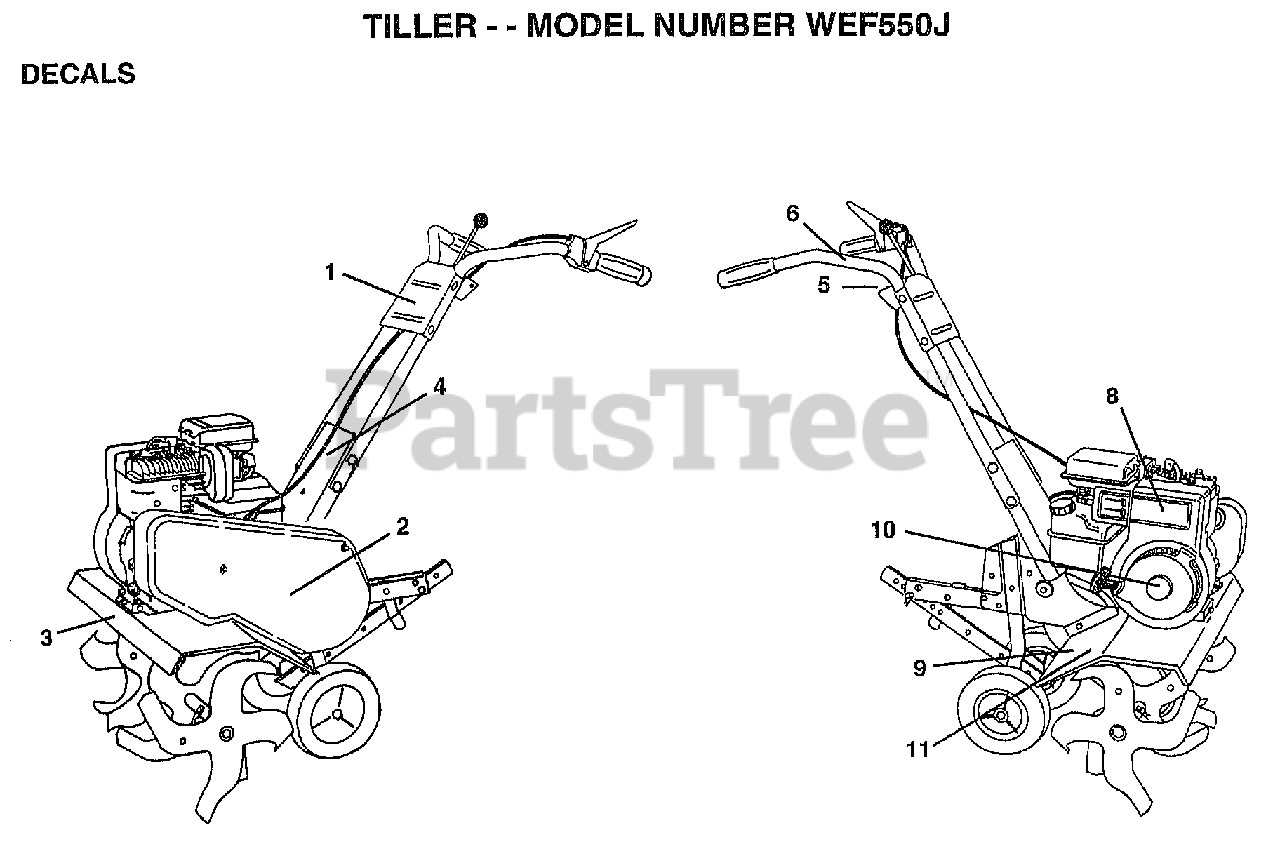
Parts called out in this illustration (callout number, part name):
1	DECAL.LOGO.CONTROL
3	DECAL.DESCRIPTION
4	DECAL.HP.REVERSE
5	DECAL REVERSE
6	DECAL TI
8	DECAL, BRIGGS & STRATTON
11	DECAL.CAUTION
